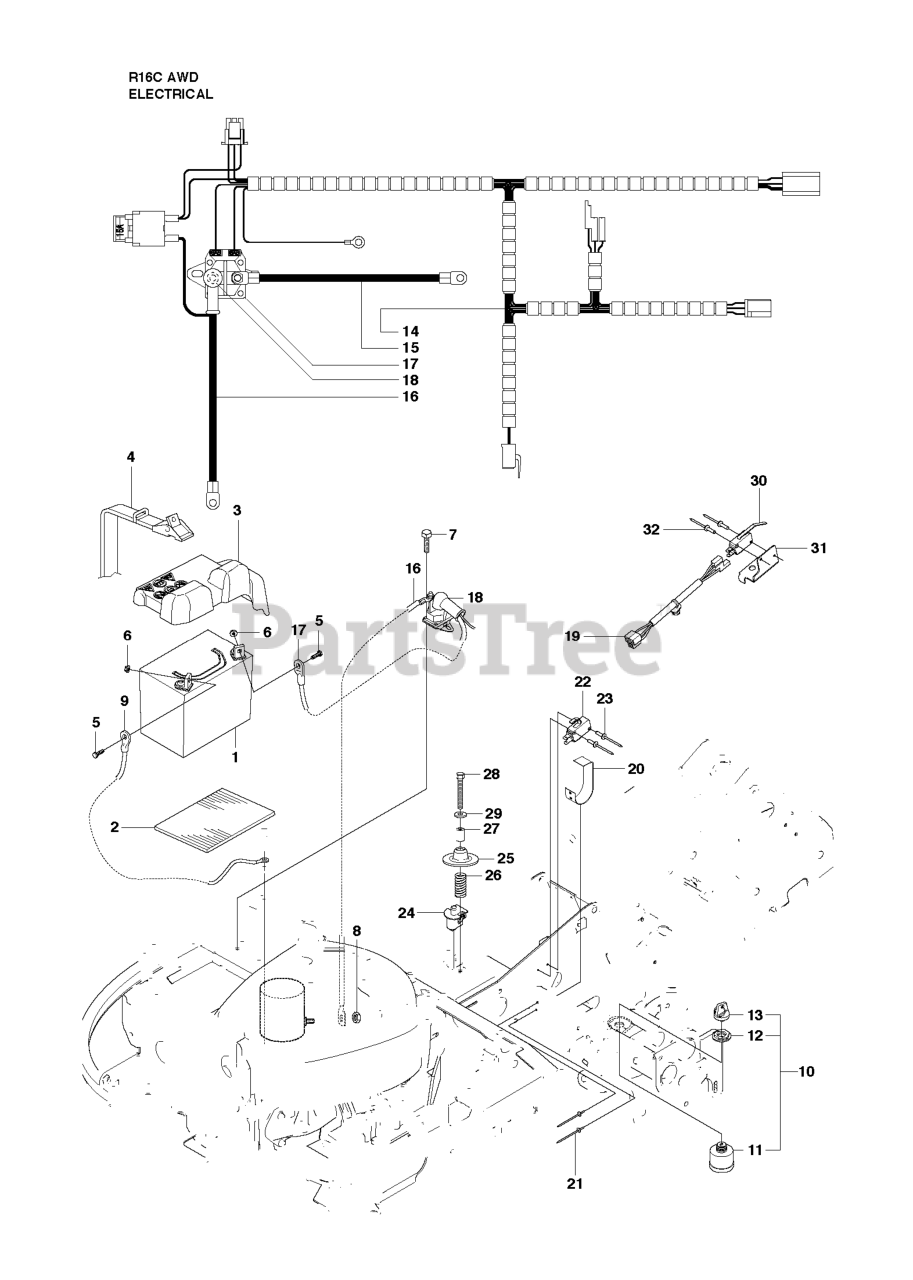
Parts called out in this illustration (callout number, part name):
5	SCREW EHHM
10	IGNITION SWITCH
11	IGNITION SWITCH
13	IGNITION KEY
19	WIRING
22	%BRAKER
27	SPACER TUBE
28	SCREW
29	WASHER BRB 8.4X17
30	RP MICRO SWITCH
